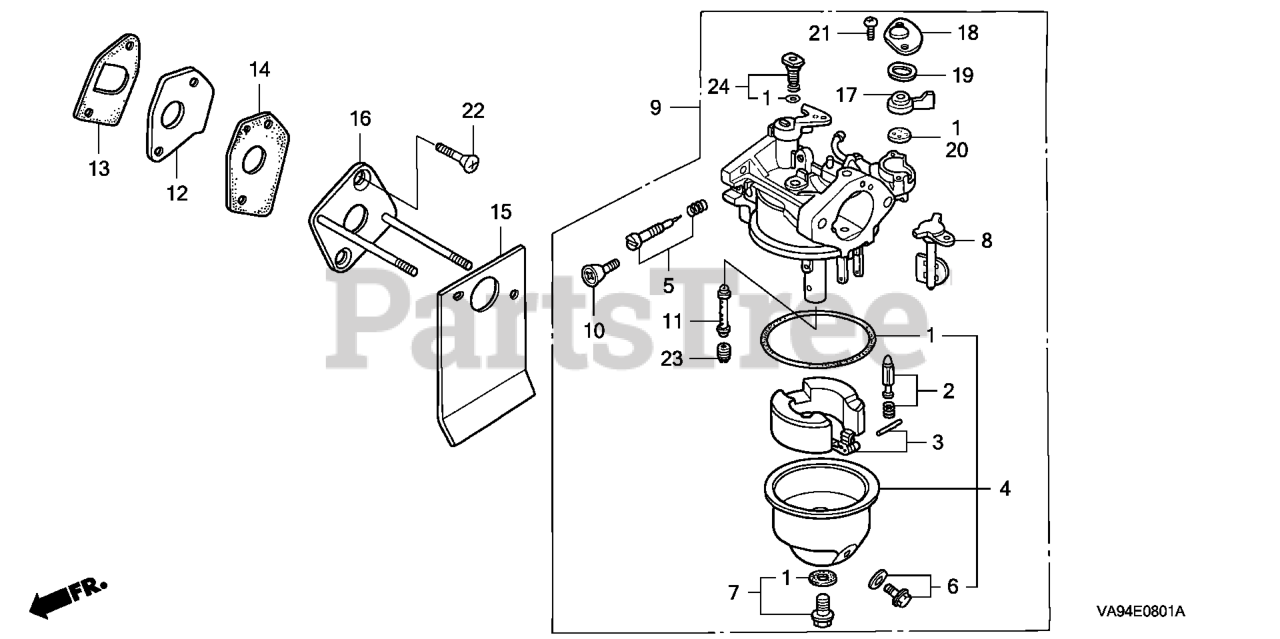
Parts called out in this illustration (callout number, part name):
1	GASKET SET
2	VALVE SET, FLOAT (CARBURETOR NO.) (SEAT NOT INCLUDED)
4	CHAMBER SET, FLOAT (CARBURETOR NO.)
5	SCREW SET, PILOT (Honda Code 1441500). (CARBURETOR NO.)
6	SCREW SET, DRAIN (Honda Code 1672187). (CARBURETOR NO.)
7	SCREW SET (CARBURETOR NO.)
9	CARBURETOR ASSY. (BF07A C)
10	SCREW, THROTTLE STOP
11	NOZZLE, MAIN
12	INSULATOR, CARBURETOR
13	GASKET, INSULATOR
14	GASKET, CARBURETOR
15	GASKET, CARBURETOR
16	PLATE, CARBURETOR JOINT
17	COVER SET COCK
17	LEVER, VALVE
18	PLATE, LEVER SETTING (CARBURETOR NO.)
19	SPRING, PETCOCK LEVER (CARBURETOR NO.)
20	GASKET, VALVE
21	SCREW, PAN (3X8) (CARBURETOR NO.)
21	SCREW, PAN (3X6)
22	SCREW, FLAT (3X6)
23	JET, MAIN (#55) Use from Engine SN BF22B D.
23	JET, MAIN (#58) (CARBURETOR NO.)
23	JET, MAIN (#60) Use up to Engine SN BF22B C.
24	JET SET, PILOT (#35)
